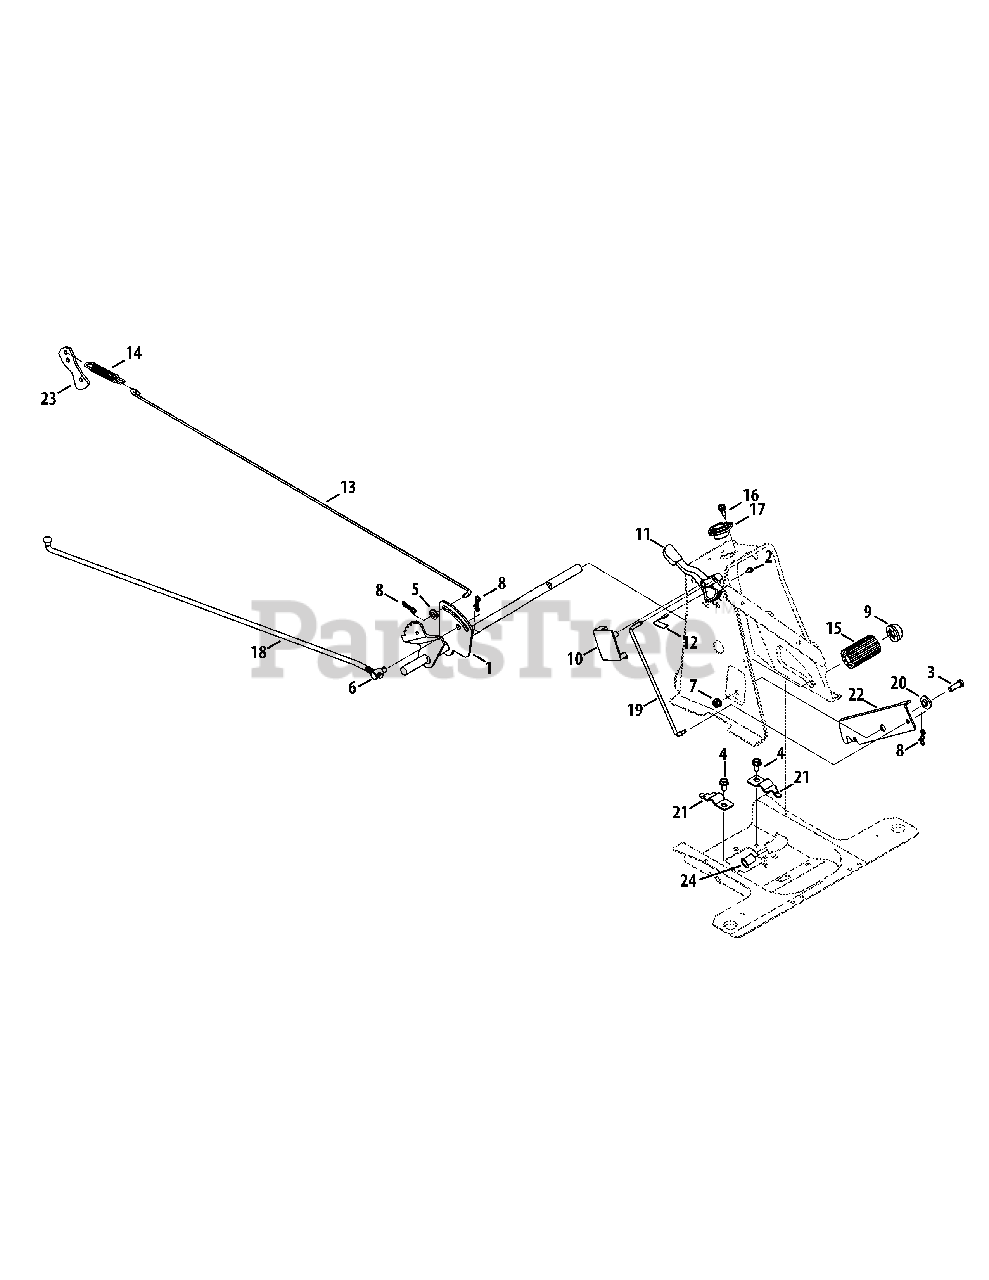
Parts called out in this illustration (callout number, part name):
1	Brake Pedal Assembly
2	Screw, #10-16:0.500
3	Hex Head Scerw, 5/16-18:1.00
4	Tap Screw, 5/16-18:.750
5	Flat Washer, .330 x .630 x .064
6	Ferrule 3/8-24 X .375 Dia.
7	Flange Lock Nut, 5/16-18
8	Bow-Tie Cotter Pin, 72
9	Push Cap, 5/8
10	Speed Control Cover
11	Speed Lever, 6-SPEED
12	Shift Spring
13	Brake Rod
14	Extension Spring, .59 OD x 4.00 LG
15	Foot Pad, 2.5" LG.
16	Shoulder Screw, .368 X.113, 1/4-20
17	Steering Col. Bearing, .880 ID X 1.36
18	Variable Speed Control Rod
19	Speed Selector Control Rod
20	Shoulder Spacer
21	Pedal Strap Support Bracket, 5/8
22	Speed Latch Bracket
23	Brake lever Bracket
24	Flange Bearing, .626 x .938 x .875
